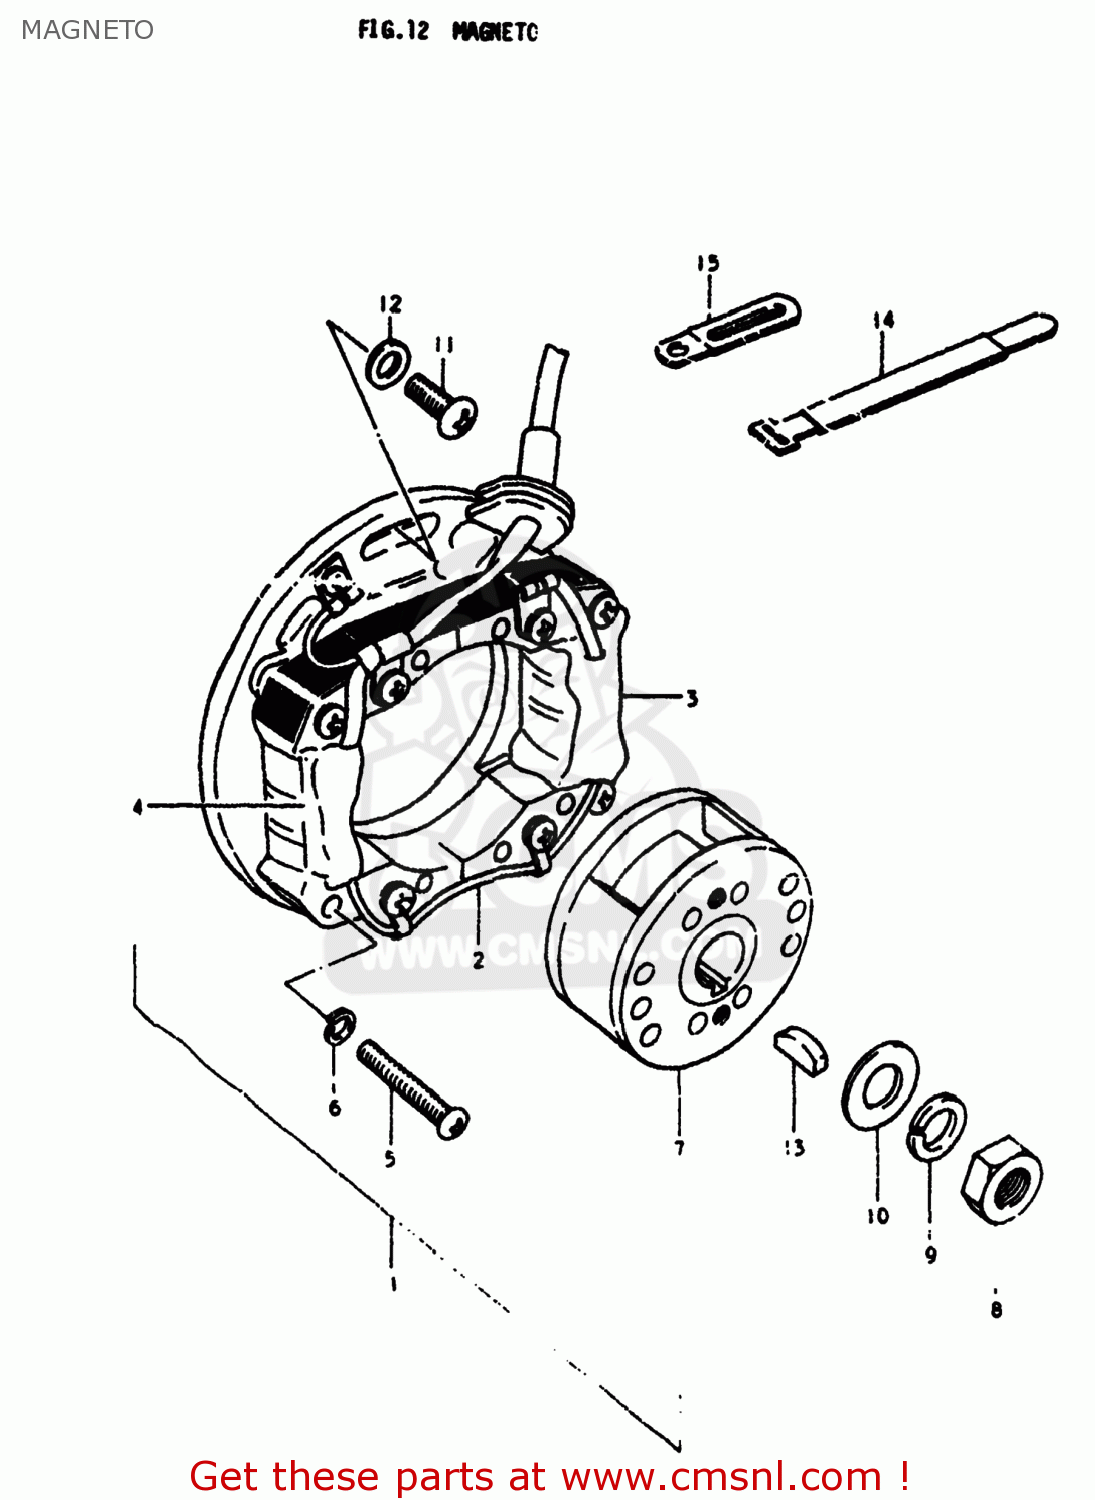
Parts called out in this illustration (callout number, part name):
1	MAGNETO ASSEMBLY
2	STATOR ASSEMBLY
3	COIL,PRIMARY
4	COIL,PULSER
5	SCREW
6	LOCK WASHER
7	ROTOR ASSEMBLY
8	NUT (10MM)
9	LOCK WASHER
10	WASHER
11	SCREW
12	WASHER
13	KEY 4MM
14	CLAMP
15	CLAMP
